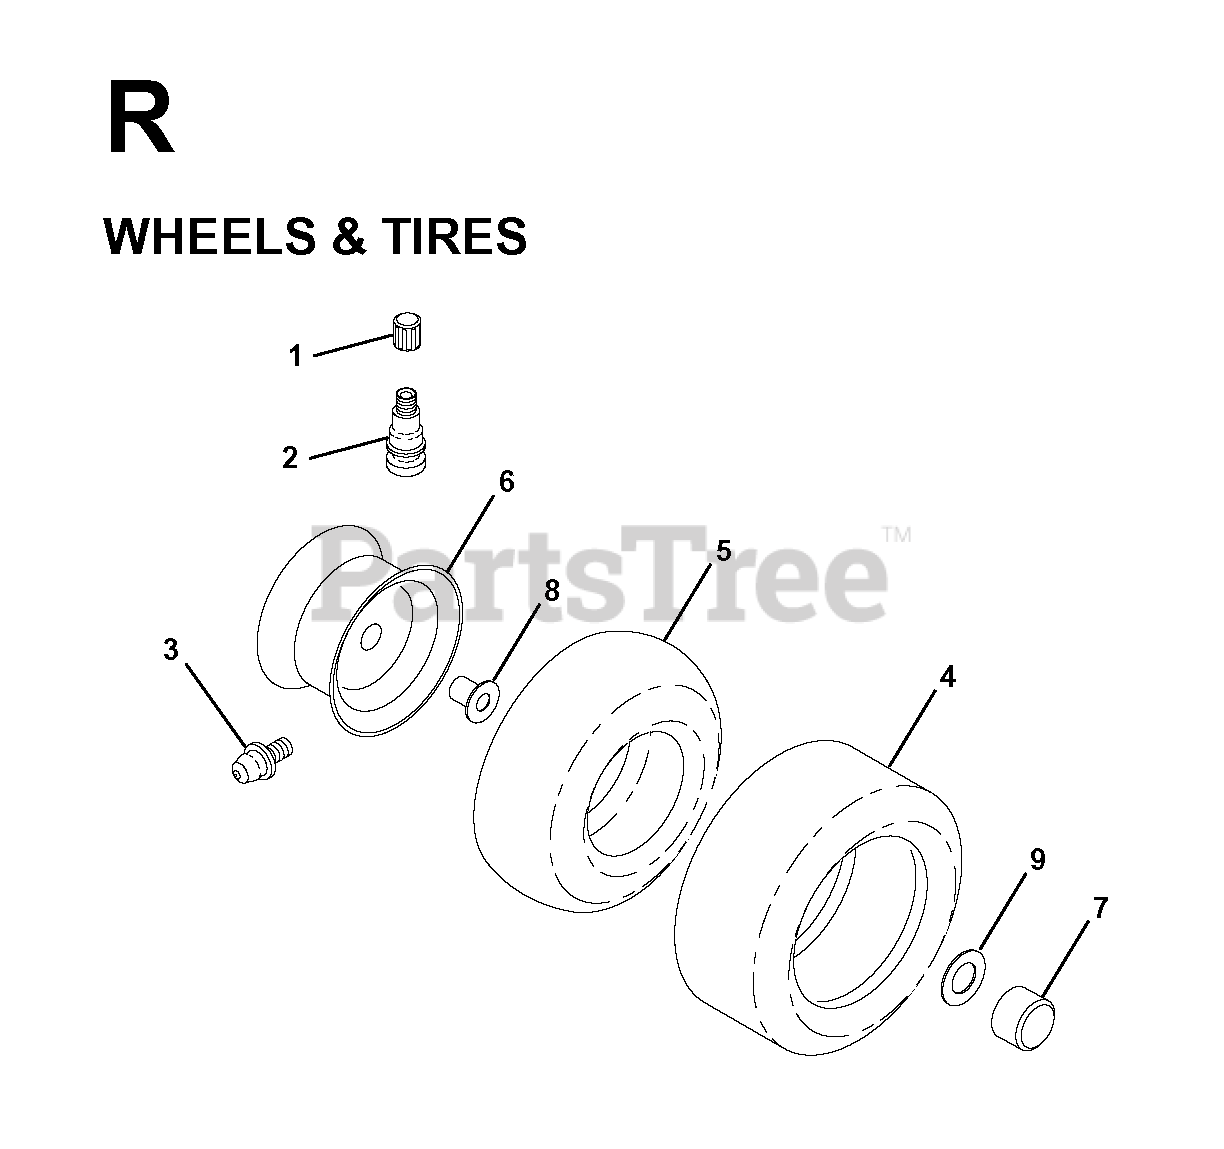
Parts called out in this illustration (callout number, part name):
1	VALVE CAP
2	VALVE STEM LT
3	FITTING LT
4	TIRE.TS 13X5-6
4	TIRE HEAVY DUTY
5	TUBE.5.3/4.5/6
5	TUBE.16X6.5/7.5-8
6	RIM
6	RIM REAR 8"
7	CAP-HUB FRONT LT
8	BEARING T
